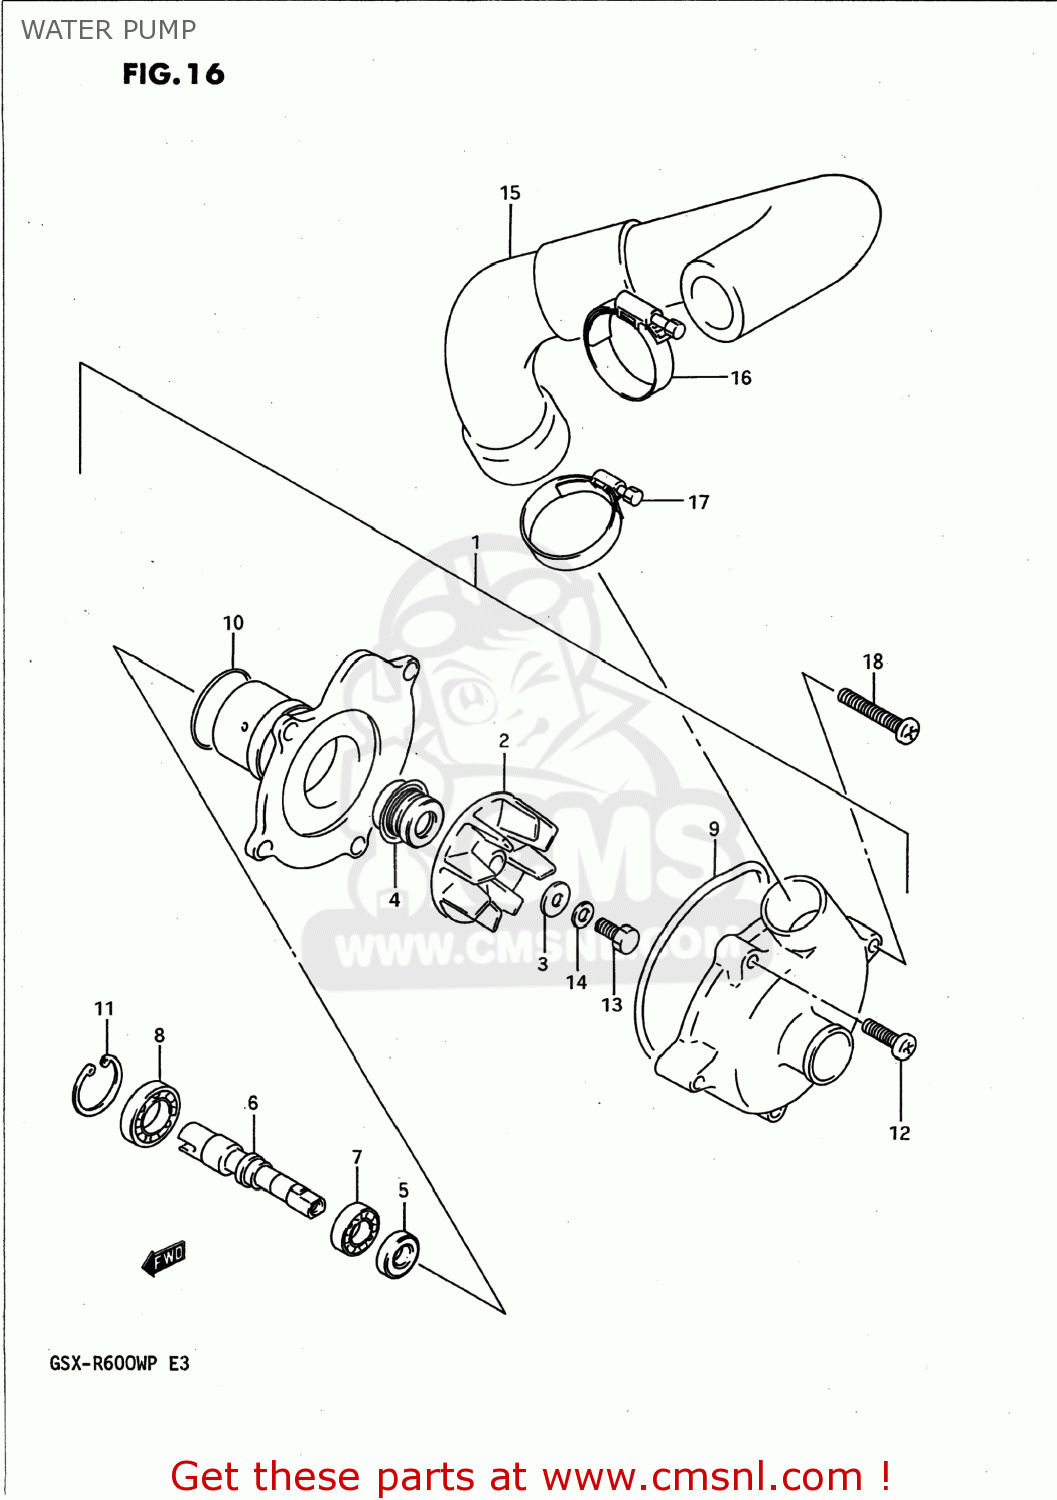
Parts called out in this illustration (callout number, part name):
1	PUMP ASSEMBLY,WATER
2	IMPELLER
3	GASKET(6X15X2.2) (NAS)
4	SEAL,MECHANICAL
5	OILSEAL
6	SHAFT
7	BEARING
8	BALL BEARING 15X28X7
9	O RING
10	O RING,WATER PUMP HOLDER
11	CIRCLIP
12	SCREW
13	BOLT(6X13)
14	WASHER
15	HOSE,WATER PUMP,OUTLET
16	CLAMP
17	CLAMP
18	SCREW
